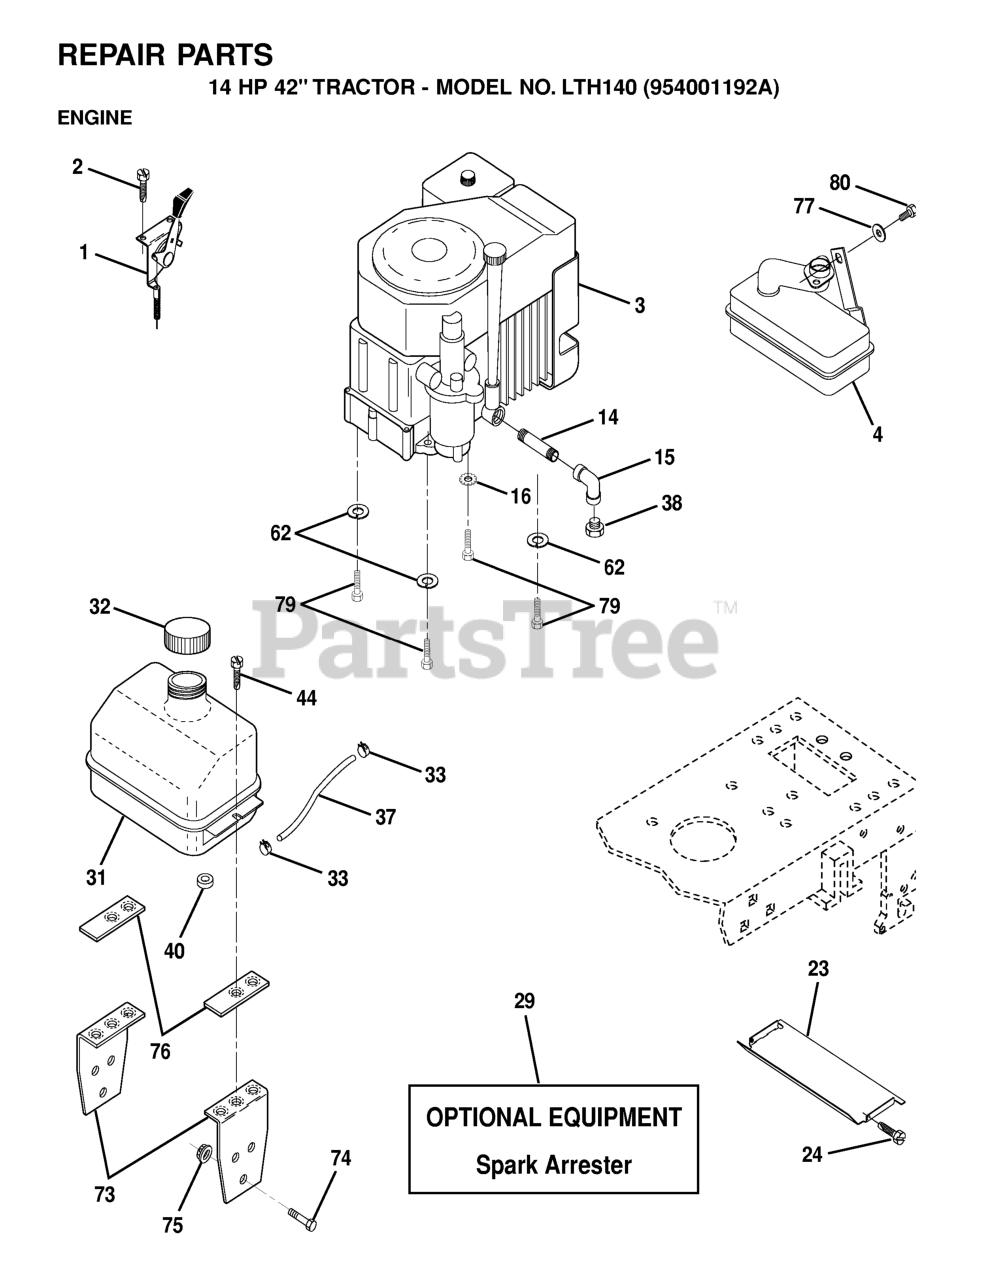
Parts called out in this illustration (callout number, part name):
1	THROTTLE CONTROL
2	SCREW LT
4	MUFFLER LT 12.5
14	Std. Pipe Nipple 3/8 - 18 NPT x 3 1/2
15	ELBOW
21	SNAP BUSHING T
23	HEAT SHIELD
29	KIT.SPARK ARRESTOR 794945 B&S
31	TANK FUEL LT
32	FUEL CAP
33	HOSE CLAMP
37	FUEL LINE T
40	SNAP BUSHING T
44	SCREW
62	WASHER.LOCK.HVY.HLCL.SPR.5/16
63	WASHER EXT TOOTH LOCK 5/16
73	BRACKET FUEL TANK T
75	NUT
76	CLAMP, FUEL TANK T
77	WASHER
79	BOLT, HEX
80	Bolt, Hex Head, Fin. 5/16-18 x 1/2
